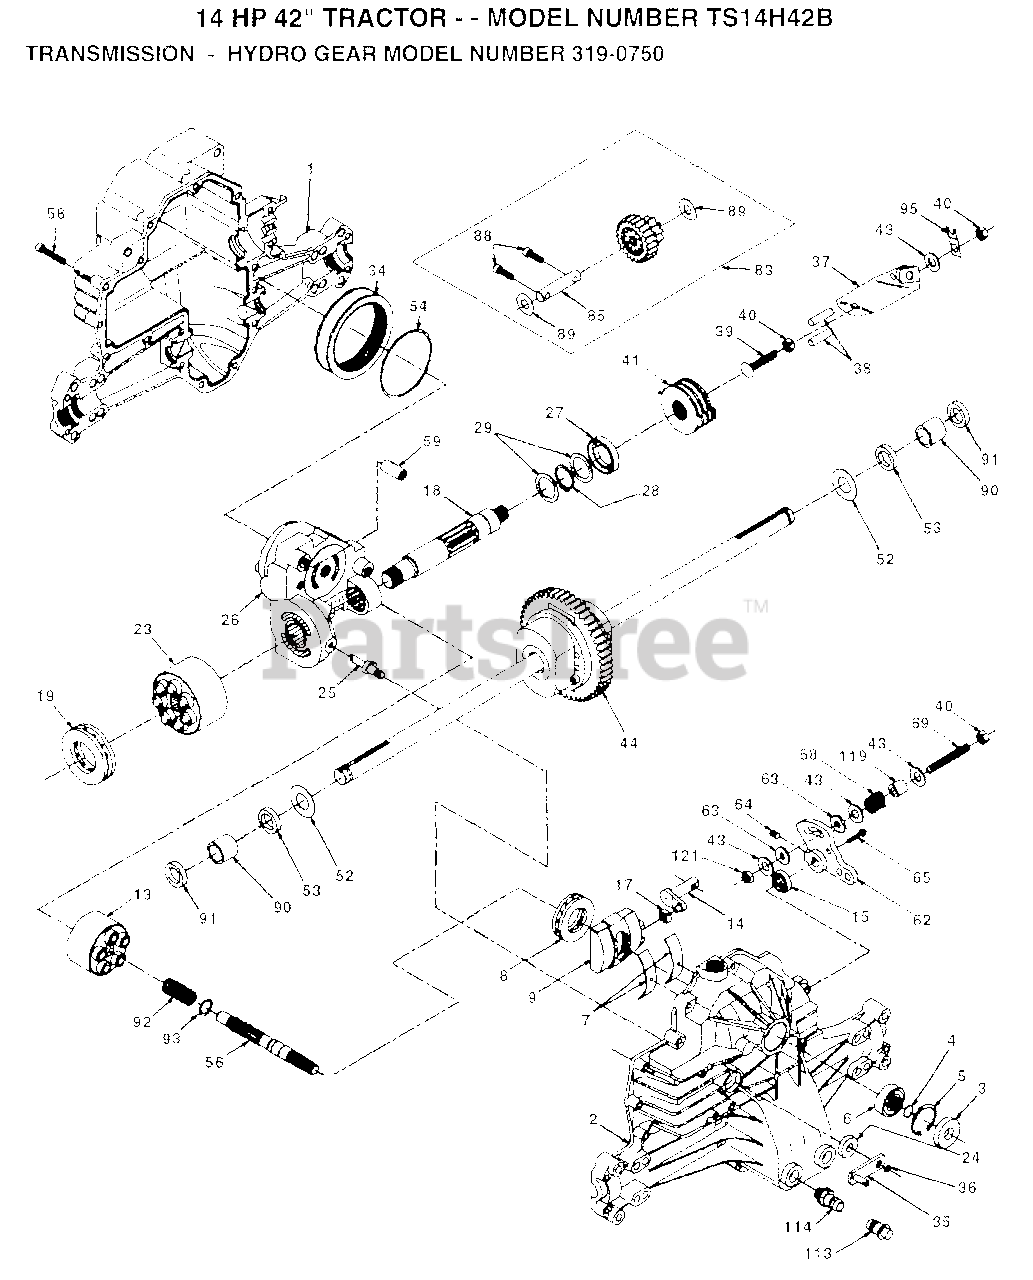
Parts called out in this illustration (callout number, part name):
1	HOUSING.L.50074RM
2	HOUSING.UP.70125
3	SEAL.9008000-0128
4	RING.RET.2003016.
5	RING.RET.2003052.
6	BEARING.(50552)42X68X16
7	CRADLE- 2003023.
8	BEARING.2003044.
9	SWASHPLT.2003087.
13	BLOCK.CLYN.70079.
14	ARM.TRUN.2003005.
15	SEAL.9008000-0126
17	GUIDE.2000015.
18	SHAFT.MOTOR.50115
19	BEARING.THS.50019
23	BLOCK.CYLIN.70082
24	SEAL.LIP.45074
25	ACTUATOR.2003555
26	KIT.CENTER.70133
27	SEAL.LIP.45075
28	RING RETAIN 50007
29	WASHER.44872
34	ELEMENT.OIL.44964
35	ARM.BYPASS.50270
36	RING.RETAIN.44870
37	ARM.ACTUAT.23710
38	PIN.ACTUAT.44891
40	NUT.LOCK.HX.50108
41	KIT.BRAKE.70135
43	WASHER HYD 44130
44	DIFFERENTIA.70130
52	WASHER.HYD.50152
53	SEAL.HYDRO.45076
54	O RING.HYD.45077
56	SHAFT.INPUT.50005
58	BOLT.1/4-20.44876
59	PIN.HYDRO.50002
62	ARM.CONTROL.50254
63	PUCK.DAMPER.50281
64	SCREW.SET.50018.
65	BOLT #8-32 X .875
68	SPRING.HYD.50277
83	JACKSHAFT/PINION GEAR.70132
85	JACKSHAFT.50086
88	SCREW.CAP.50154.
89	WASHER.HYD.50132
90	BEARING.SLV.50118
91	SEAL.WIPER.50941
92	SPRING.2003014.
93	WASHER.2003017
113	CAP.VENT.70109
114	O-RING.ASM.70110
119	SPACER.HYD.50278
